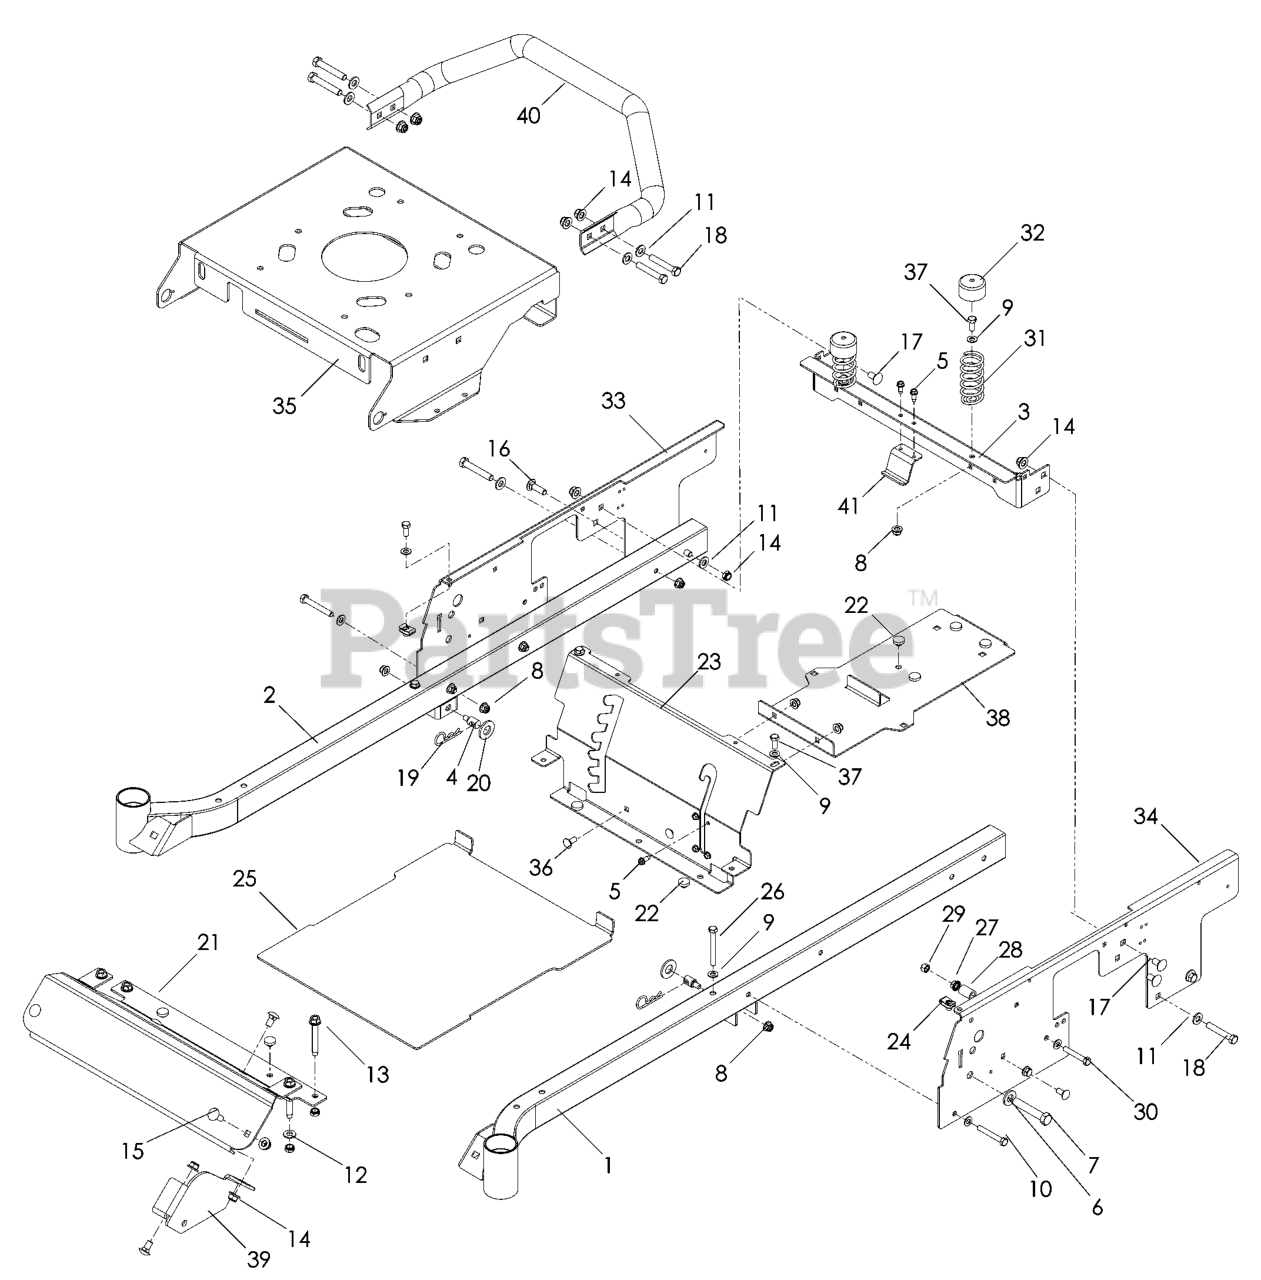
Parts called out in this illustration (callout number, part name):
1	FRAME TUBE, LH
2	FRAME TUBE, RH
3	SUPPORT, REAR SEAT
4	STUD w/ ANTI-ROTATE
5	SCREW ¼-20 x 5/8 SLF TAP
6	WASHER ½ SAE
7	HCS ½-13 x 2¾
8	NUT 5/16-18 FLANGE NYLOC
9	WASHER 5/16 SAE FLAT
10	HCS 5/16-18 x 2¼
11	WASHER 3/8 SAE FLT
12	NUT 3/8-16 HEX JAM NYLOC
13	BOLT 3/8-16 x 25/8 THD FRM
14	NUT 3/8-16 FLANGE NYLOC
15	RHSNB 3/8-16 x 1
16	RHSNB 3/8-16 x 1¼
17	RHSNB 3/8-16 x ¾
18	HCS 3/8-16 x 2¼
19	HAIRPIN
20	WASHER 5/8 SAE FLT
21	FOOT REST
22	GROMMET,BUMPER
23	PANEL, SEAT SUPPORT
24	U TYPE RETAINER
25	FOOT PLATE
26	HCS 5/16-18 x 2¾
27	NUT 5/16-18 HEX WHIZLK
28	BUSHING
29	NUT 5/16-18 HEX NYLOC
30	HCS 5/16-18 x 2
31	SPRING, SEAT
32	CAP, SPRING
33	PLATE, RH
34	PLATE, LH
35	PLATE, ENGINE
36	RHSNB 5/16-18 x ¾
37	HCS 5/16-18 x ¾
38	SUPPORT, TANK
39	BRACKET, FRONT DECK
40	GUARD, REAR
41	BRACKET, FUEL TANK
